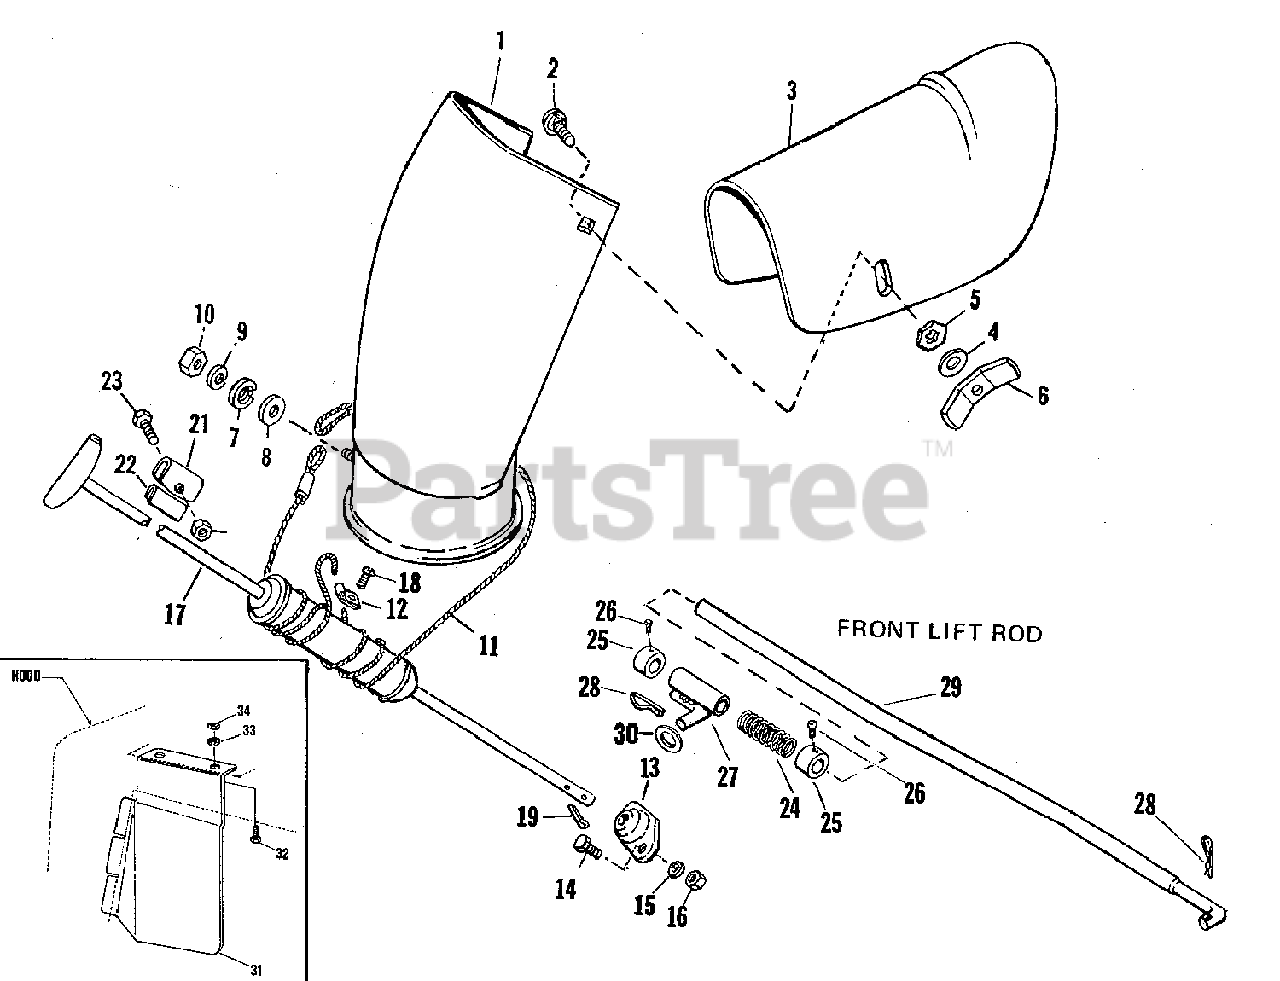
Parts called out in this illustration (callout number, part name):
1	SPOUT ASSEMBLY
2	BOLT, Carriage, 5/16-18 x 3/4
3	EXTENSION, Spout
4	WASHER, Flat, 3/8
5	WASHER, Lock, Special
6	NUT, Wing, 5/16-18
8	WASHER, Flat, 1/4
9	WASHER, Lock, 5/16
10	NUT, Hex, 5/16-18
11	CABLE ASSEMBLY
14	SCREW, Hex Cap, 1/4-20 x 5/8
15	WASHER, Lock, 1/4"
16	NUT, Hex, 1/4-20
17	TUBE ASSEMBLY, Spout Control
18	SCREW, Taptite, 1/4-20 x 3/8
19	PIN, Cotter, 3/32 x 5/8
20	NUT, Hex Lock, 5/16-18
22	LINER, Guide
23	SCREW, Hex Cap, 5/16-18 x 1-1/4
26	SCREW, Set, 5/16-18 x 3/8
27	GUIDE ASSEMBLY, Rod
28	CLIP, Hair Pin, 1/8 Diameter
30	WASHER, Flat, 17/32 x 1-1/4
31	DEFLECTOR, Snow
32	SCREW, Hex Cap, 1/4-20 x 1/2
34	NUT, Hex, 1/4-20
